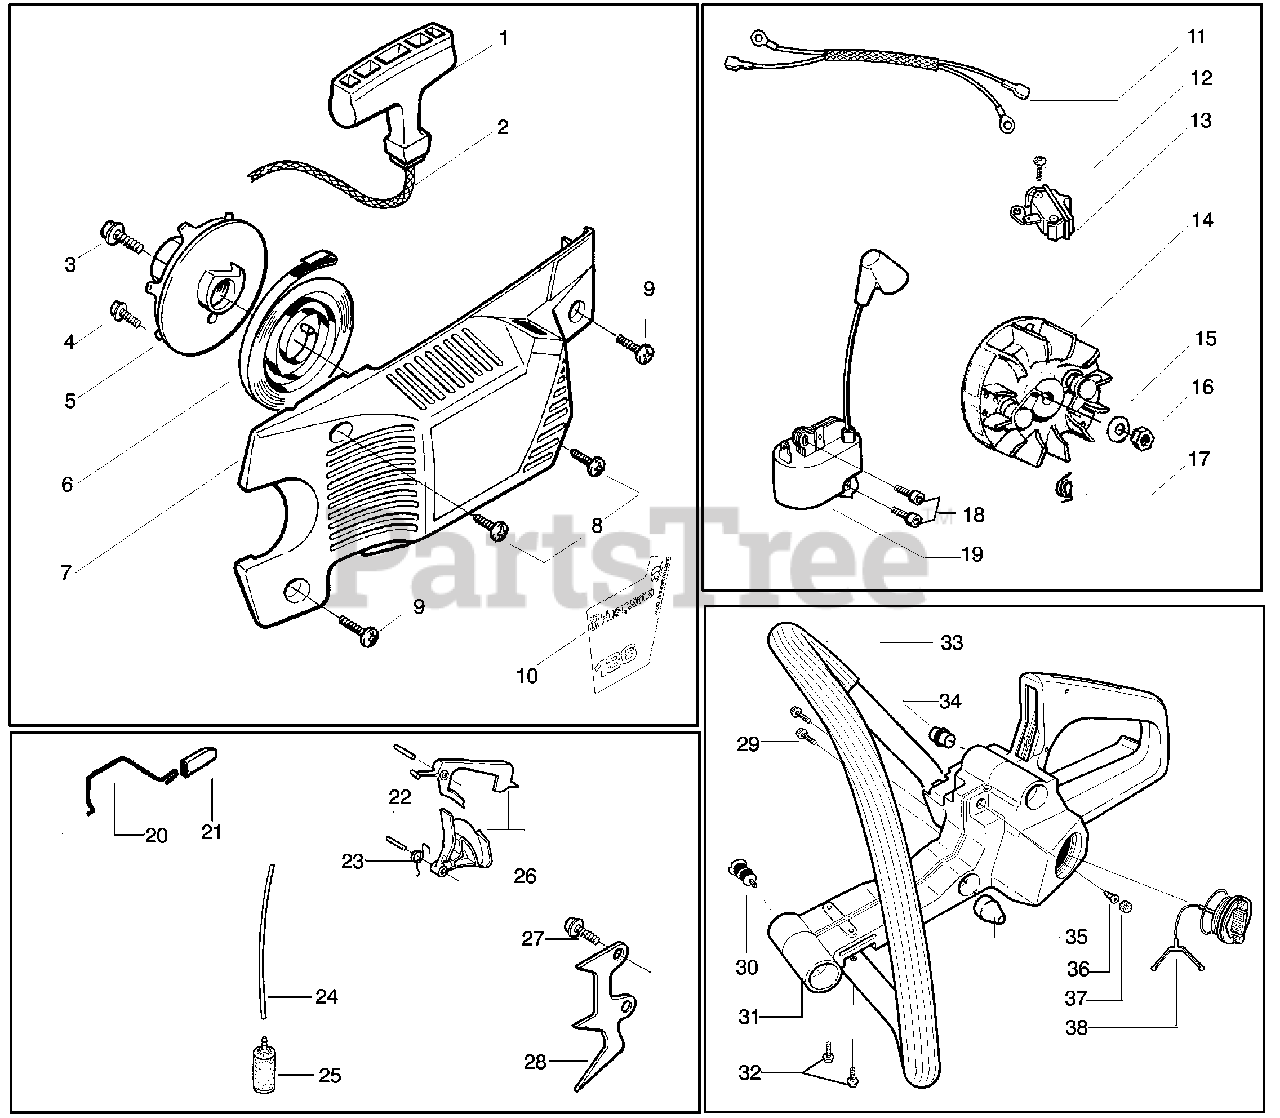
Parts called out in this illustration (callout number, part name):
1	Starter Handle
5	Starter-Pulley Kit
6	Recoil Spring
7	Fan Housing Assembly
10	Decal -Model
11	Leadwire Harness Ass'y.
13	Ignition Switch
14	Assy. Flywheel
15	Flywheel Washer
17	Spring -Starter Dog
19	Module - Ignition
20	Wire - Throttle
21	Cap - Wire
24	Kit - Fuel line
25	Assy. Fuel Pickup
26	Kit - Throttle Trigger
28	Assy. Spike
31	Assy. -Tank/Handle
33	Handle-Front
34	Isolator - Limiter
35	Isolator Bumper
36	Valve - Check
37	Plug - Vent
38	Kit-Fuel Cap-Assy
